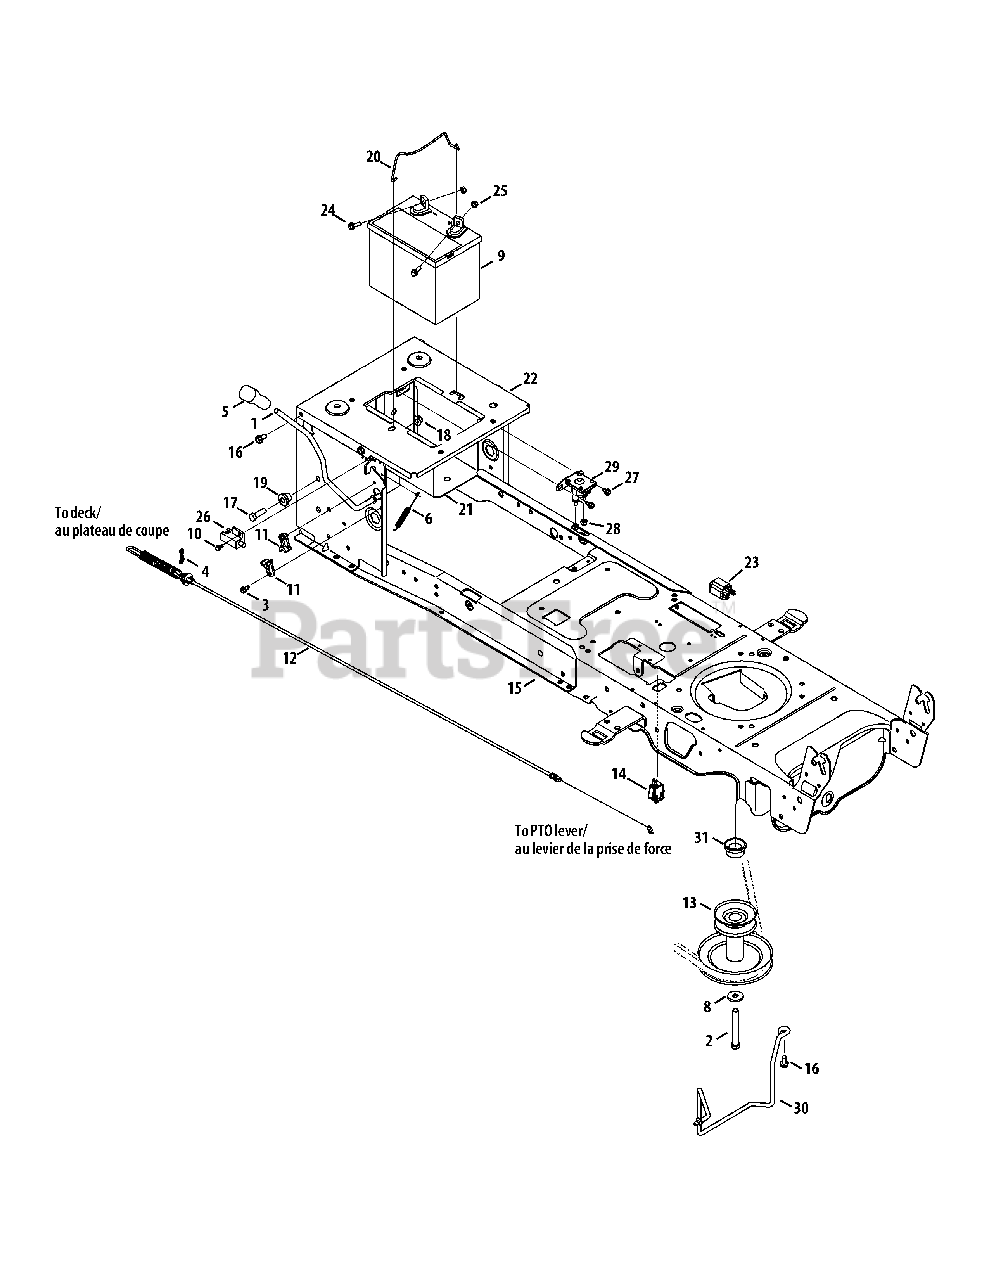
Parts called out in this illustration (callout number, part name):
1	Handle Ass’y , PTO
2	Hex Screw 7/16-20 x 3.5 Gr. 5
3	Hex Wash S-Tapp Scr 1/4-20 x .50
4	Bow-Tie Cotter Pin
5	Handle Grip 3/8
6	Extension Spring .38 Dia. x 5.6
7	Lockwasher 7/16 ID
8	Flat Washer .450 x 1.25 x .164
9	Battery 245 CCA (Dry)
10	Shoulder Screw #10-32 x .50
11	Bearing, PTO
12	Deck Engagement Cable
13	Engine Pulley 3.56 x 6.12 Dia.
14	Switch, Plunger, snap mount
15	Lower Frame Ass’y
16	Hex Wash Hd. Tapp Scr. 5/16-18 x .75
17	Hex Bolt 3/8-16 x 1.25
18	Flange Lock-Nut 3/8-16 Gr. F Ny lon
19	Shoulder Spacer .38 x 1.0 x .70
20	Battery Retainer Rod
21	Battery Tray
22	Seat Frame Bracket
23	Switch, 3-Pole,
24	Hex Hd. Flg. Scr. 1/4-20 x .75 Gr. 5
25	Sems Hex Nut 1/4-20
26	Switch, In ter lock
27	Hex Wash HD Tapp Scr 1/4-20 x .375
28	Hex L-Flanged Nut 1/4-20 Gr. F Ny lon
29	Solenoid
30	Belt Keeper Rod
